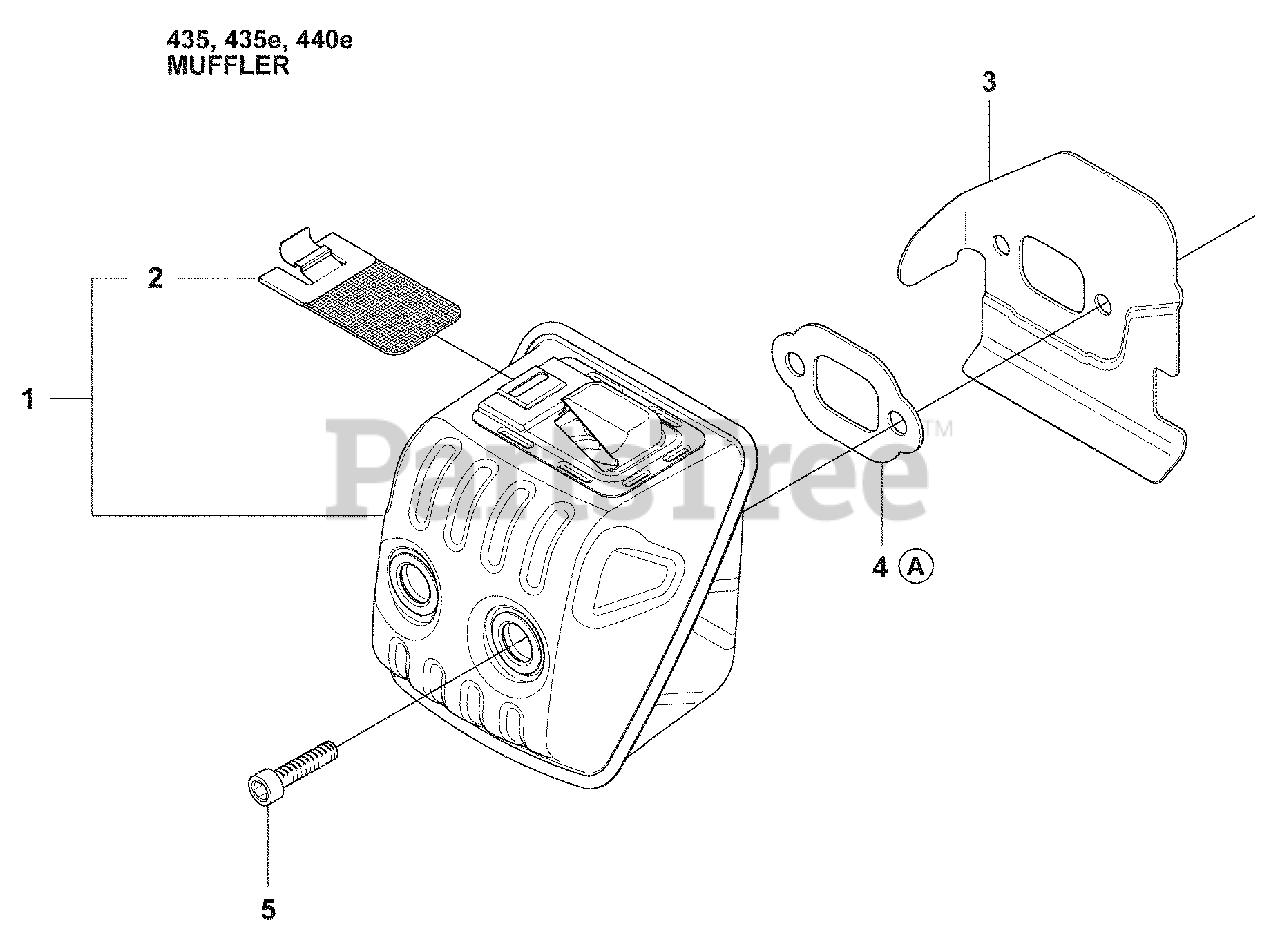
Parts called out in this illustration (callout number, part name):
1	Muffler Assembly
2	Spark Arrester
3	Heat Deflector
4	Gasket
5	Screw, IHSCM
